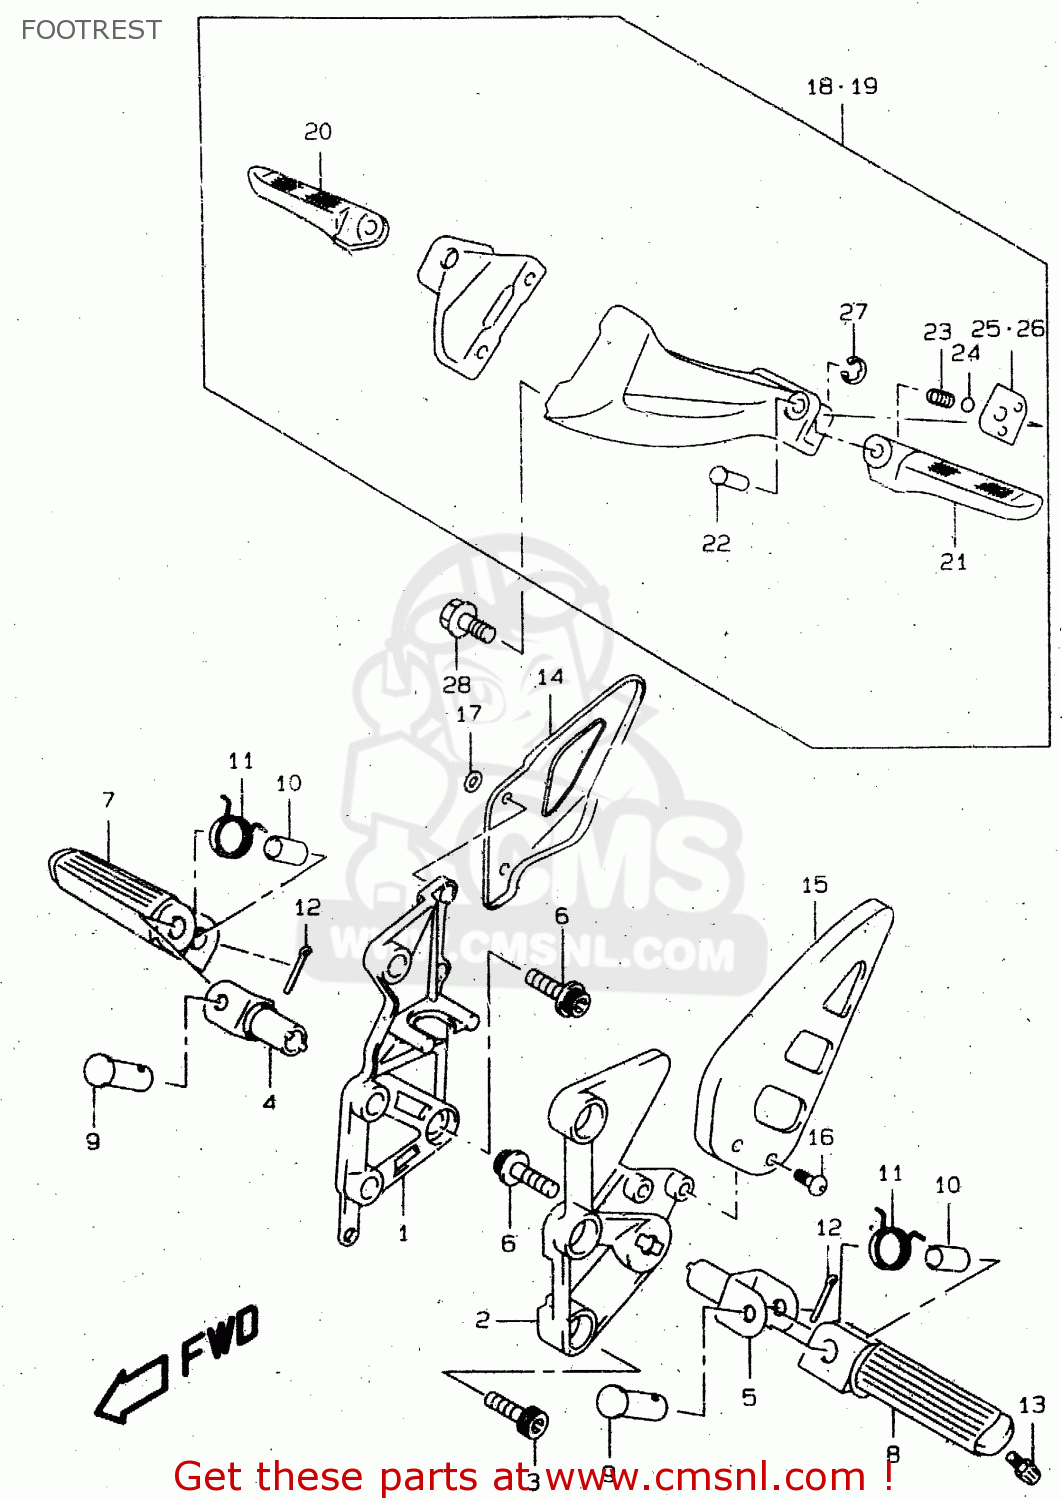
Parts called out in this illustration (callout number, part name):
1	BRACKET,FR FOOTREST,R
2	BRACKET,FR FOOTREST,L
3	BOLT
4	HOLDER,FOOTREST,R
5	HOLDER,FOOTREST,L
6	BOLT(10X28)
7	BAR,FR FOOTREST,R
8	BAR,FR FOOTREST,L
9	PIN
10	SPACER(8.1X12X22)
11	SPRING
12	PIN 20X15
13	BOLT,BANK SENSOR
14	GUARD,FR FOOTREST,R
15	GUARD,FR FOOTREST,L
16	SCREW(5X10)
17	WASHER(6.5X16X1)
18	FOOTREST ASSY,PILLION,R
19	FOOTREST ASSY,PILLION,L
20	BAR,PILLION FOOTREST,RIGHT
21	BAR,PILLION FOOTREST,LEFT
22	PIN
23	SPRING
24	BALL
25	PLATE,PILLION,RIGHT
26	PLATE,PILLION,LEFT
27	E-RING
28	BOLT
